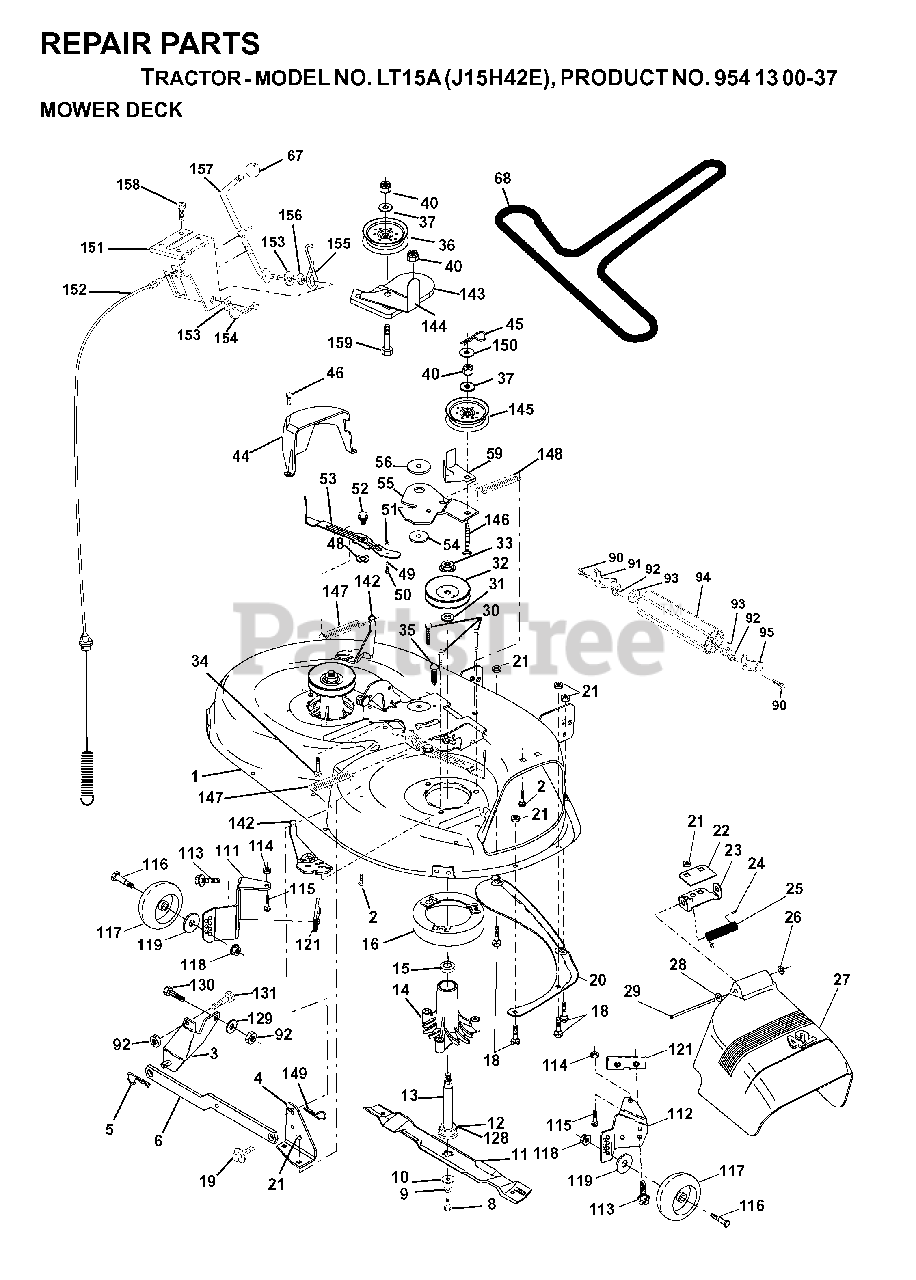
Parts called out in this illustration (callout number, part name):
1	42" DECK KIT
2	BOLT
3	BRKT ASM SWAY BAR
4	BRACKET SWAY BAR 42" DECK
5	RETAINER-SPRNG RB
6	REAR SUSP ARM
8	BLADE BOLT
9	LOCKWASHER
10	WASHER.BLADE
12	BEARING
13	SHAFT ASM VENT
14	HSG MANDREL
16	STRIPPER
17	BOLT
18	BOLT
19	BOLT SHD 5/16-18
20	BAFFLE.VORTEX
21	LOCKNUT
22	STIFFENER BRACKET
23	DEFLECTOR BRACKET
24	CAP-SLEEVE LT
25	SPRING TORSION
26	NUT PUSH M
27	SHIELD DEFLECTOR
28	WASHER
29	ROD.HINGE
30	SCREW THDROL ROLLING WASHER HD
31	WASHER
32	PULLEY/MANDREL
33	NUT
34	BOLT
35	FASTENER.XMAS.TREE
36	FLAT IDLER PULLEY
40	LOCKNUT
44	GUARD MANDREL LH BLACK
45	RETAINER M
46	SCREW.1/4-20X5/8
49	ROLLER ASSY
50	BOLT
53	ARM
54	HARDENED WASHER
55	ARM IDLER 42" MOWER LT/YT
56	SPACER.RETAINER.MOWER
59	GUARD, BELT
67	KNOB T (3/8 HOLE)
68	BELT V SECONDARY
90	BOLT
91	BRACKET LH (A)
92	NUT
94	NOSE ROLLER
95	BRACKET RH (B)
111	BRACKET WHEEL GAUGE LH 42" DK
112	BRACKET WHEEL GAUGE RH 42" DK
113	SCREW 5/16"
114	NUT
115	BOLT
117	WHEEL.GAUGE.STANDARD
118	LOCKNUT
119	WASHER
121	BRACKET.EXTRD.GWL
128	WASHER FELT
129	WASHER
130	BOLT
131	BOLT D
142	ARM SPRING BRAKE MOWER
143	BRACKET, ARM IDLER
144	KEEPER.BELT.42".CLUTCH.CABLE
145	PULLEY
146	BOLT, CARRIAGE IDLER
147	SPRING EXTENSION
148	IDLER RETURN SPRING
149	SPRING.RETAINER.YELLOW.ZINC
150	WASHER PM
151	BRACKET, CLUTCH CABLE
152	CLUTCH CABLE 42"
153	WASHER FLAT 3/8"
154	SPRING RETAINER
155	SPRING RETENTION LEVER
156	SPACER CLUTCH CABLE
157	ROD CLUTCH CABLE 3/8"
158	SCREW LT
159	BOLT
